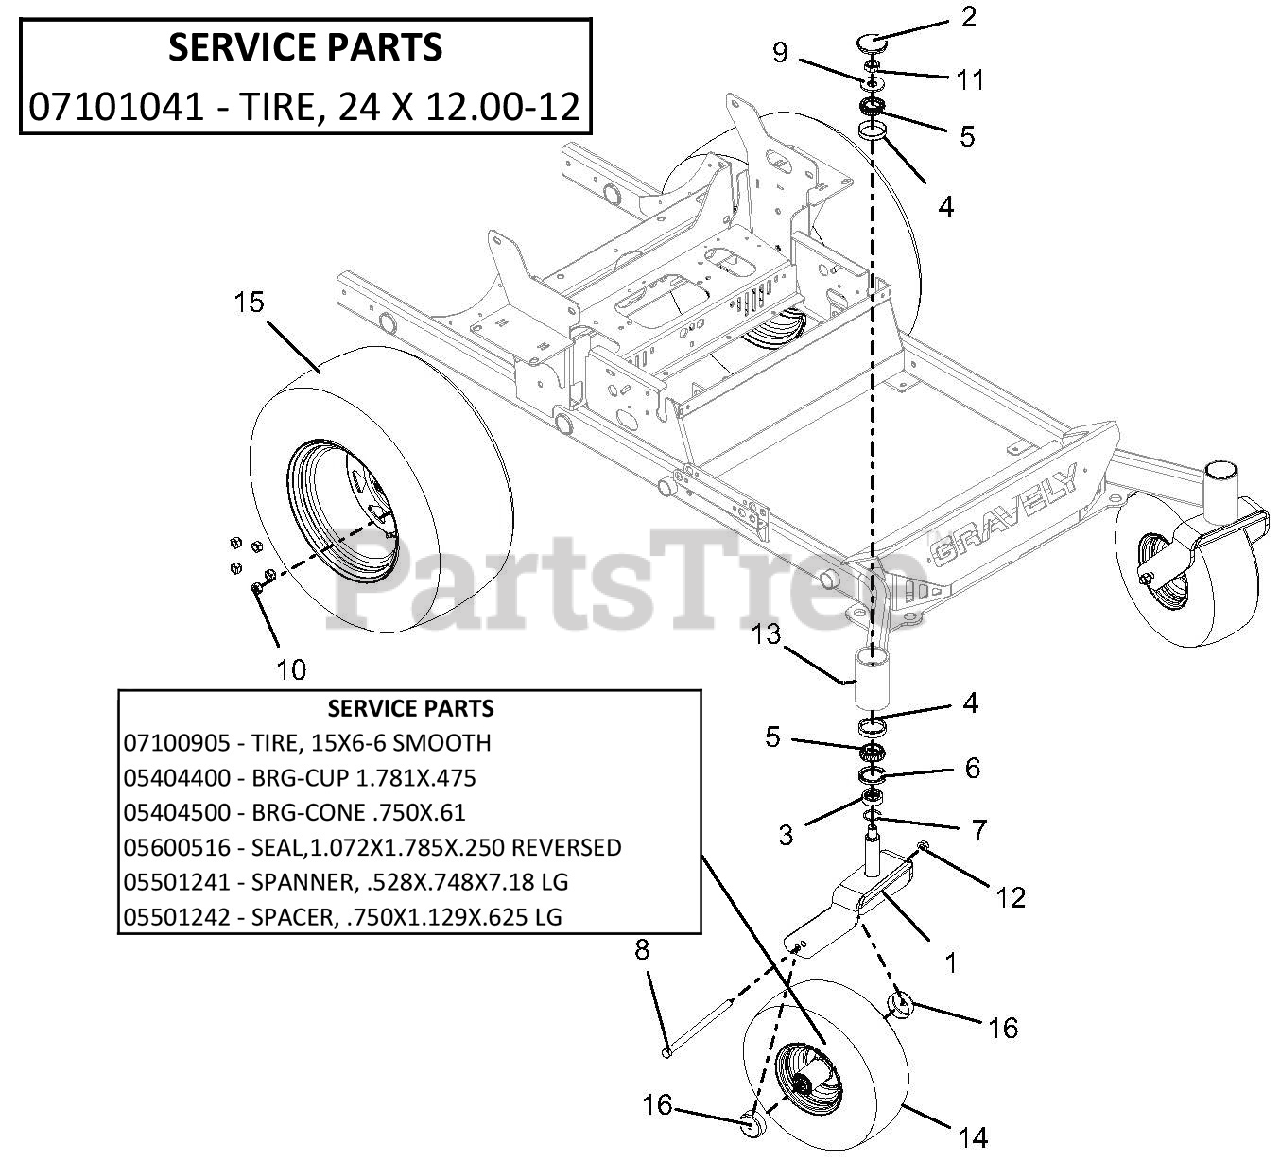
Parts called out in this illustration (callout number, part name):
1	CASTER FORK WMT - RED
2	CAP, DUST
3	SPCR, FRONT CASTER FORK
4	BRG-CUP 2.328X.465
5	BRG-CONE 1.25X.66
6	SEAL, OIL 1.75 X 2.332 X .312
8	@BLT-HEX .50-13X9.00 GR5 YWZC
9	@WSHR-FL-STL.812X2.00X.148YWZC
10	WHEEL NUT .500-20 YZ
11	NUT-JAM TOPLK .75-16 YWZC
12	@NUT-LK-TOP-FLG .50-13 YWZC
13	FTG, .25-28 FLUSH MNT GREASE
14	TIRE/WHEEL 15X6.00-6 SMOOTH
14	TIRE, 15X6-6 SMOOTH
14	BRG-CONE .750X.61
14	BRG-CUP 1.781X.475
14	SEAL,1.072X1.785X.250 REVERSED
14	SPANNER, .528X.748X7.18 LG
14	SPACER, .750X1.129X.625 LG
15	TIRE/WHEEL ASSM, 24X12-12
15	TIRE, 24 X 12.00-12
16	SHIELD, WHEEL BEARING
